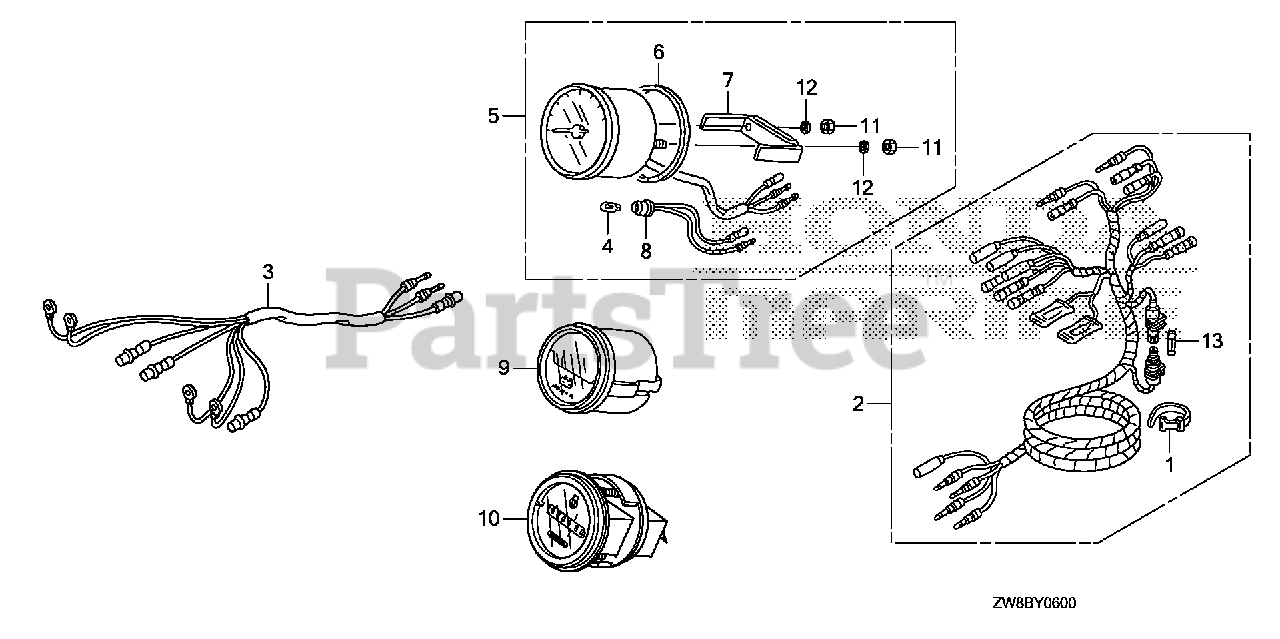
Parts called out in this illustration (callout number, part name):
1	BAND B1, WIRE
2	HARNESS ASSY., METER (A)
3	HARNESS ASSY., METER (B)
4	BULB, WEDGE BASE (T10) (12V 1.7W) (STANLEY)
5	TACHOMETER ASSY.
6	GASKET
7	BRACKET
8	SOCKET
9	METER ASSY., VOLT
10	METER ASSY., HOUR L.C.D.
11	NUT, HEX. (5MM)
12	WASHER, SPRING (5MM)
13	FUSE A (10A)
